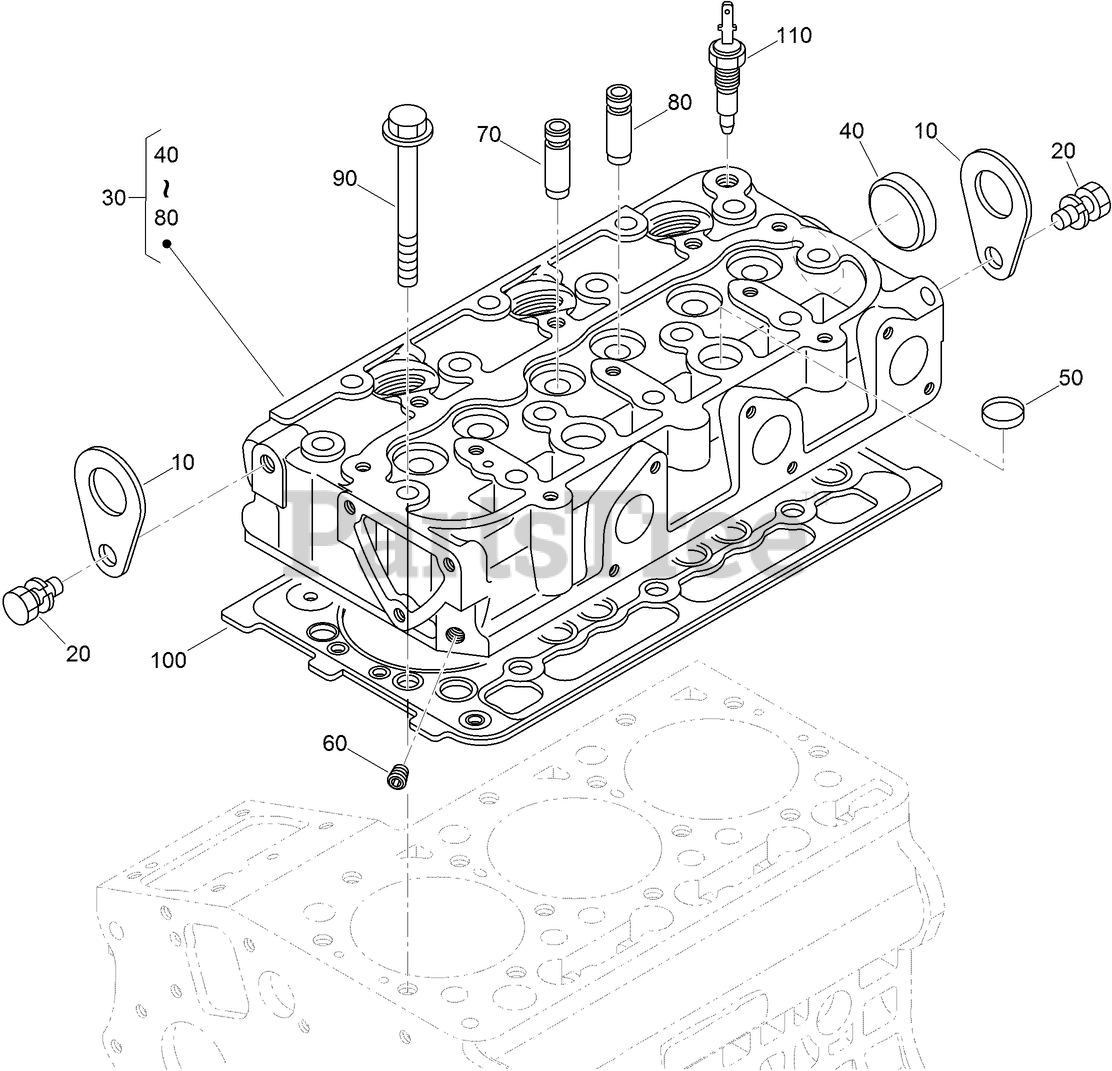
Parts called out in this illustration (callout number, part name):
10	HOOK-ENGINE
30	CYLINDER HEAD ASM
40	CAP-SEALING
50	CAP-SEALING
70	GUIDE-VALVE, INLET
80	GUIDE-VALVE, EXHAUST
90	BOLT-HEAD, CYLINDER
100	GASKET-HEAD, CYLINDER
110	THERMOSWITCH
